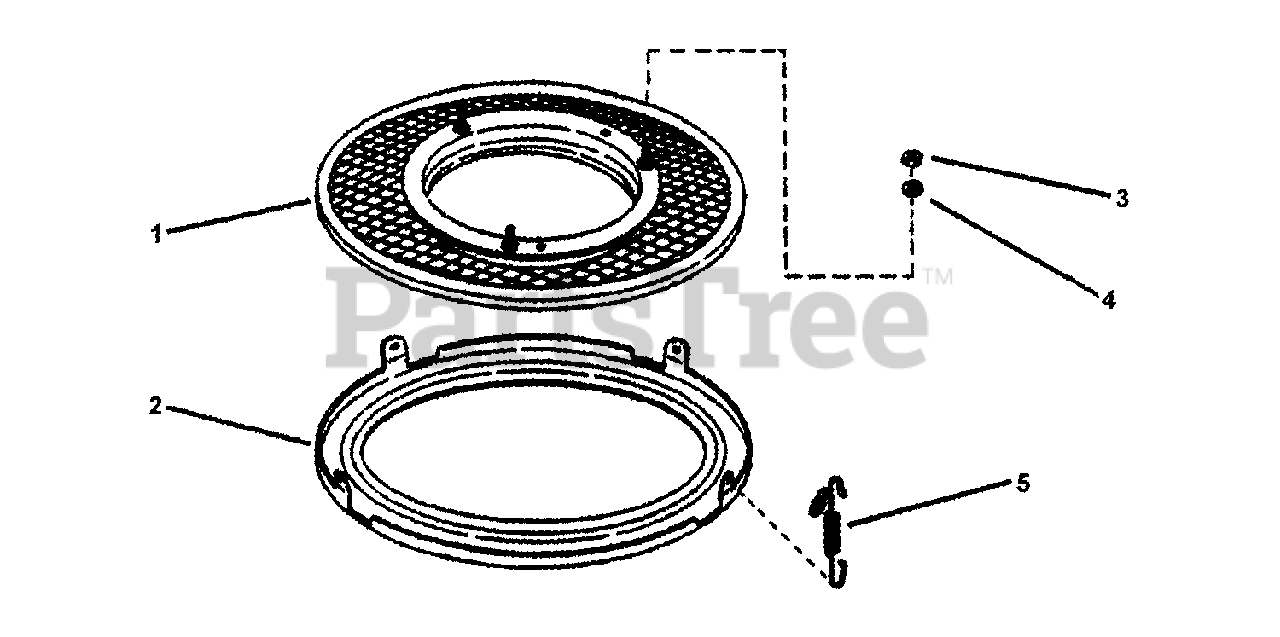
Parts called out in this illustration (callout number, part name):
1	SCREEN, Fastener Assembly
2	RING, Bottom (21.77" Inside Diameter)
2	RING, Bottom (22.60" Inside Diameter)
3	NUT, 5/16-24 Hex, GR5
4	WASHER, 5/16" Split Lock
5	SPRING, Latch
